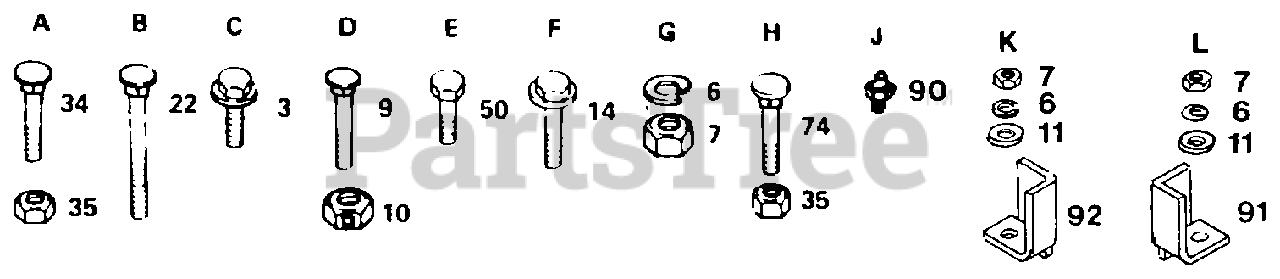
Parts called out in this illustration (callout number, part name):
3	SCREW LT
6	LOCKWASHER
7	NUT.HEX.5/16-18
9	BOLT
11	WASHER
14	SCREW
22	BOLT
34	BOLT
50	BOLT
74	BOLT
90	ZERK M
91	BRACKET RH M
92	BRACKET T
